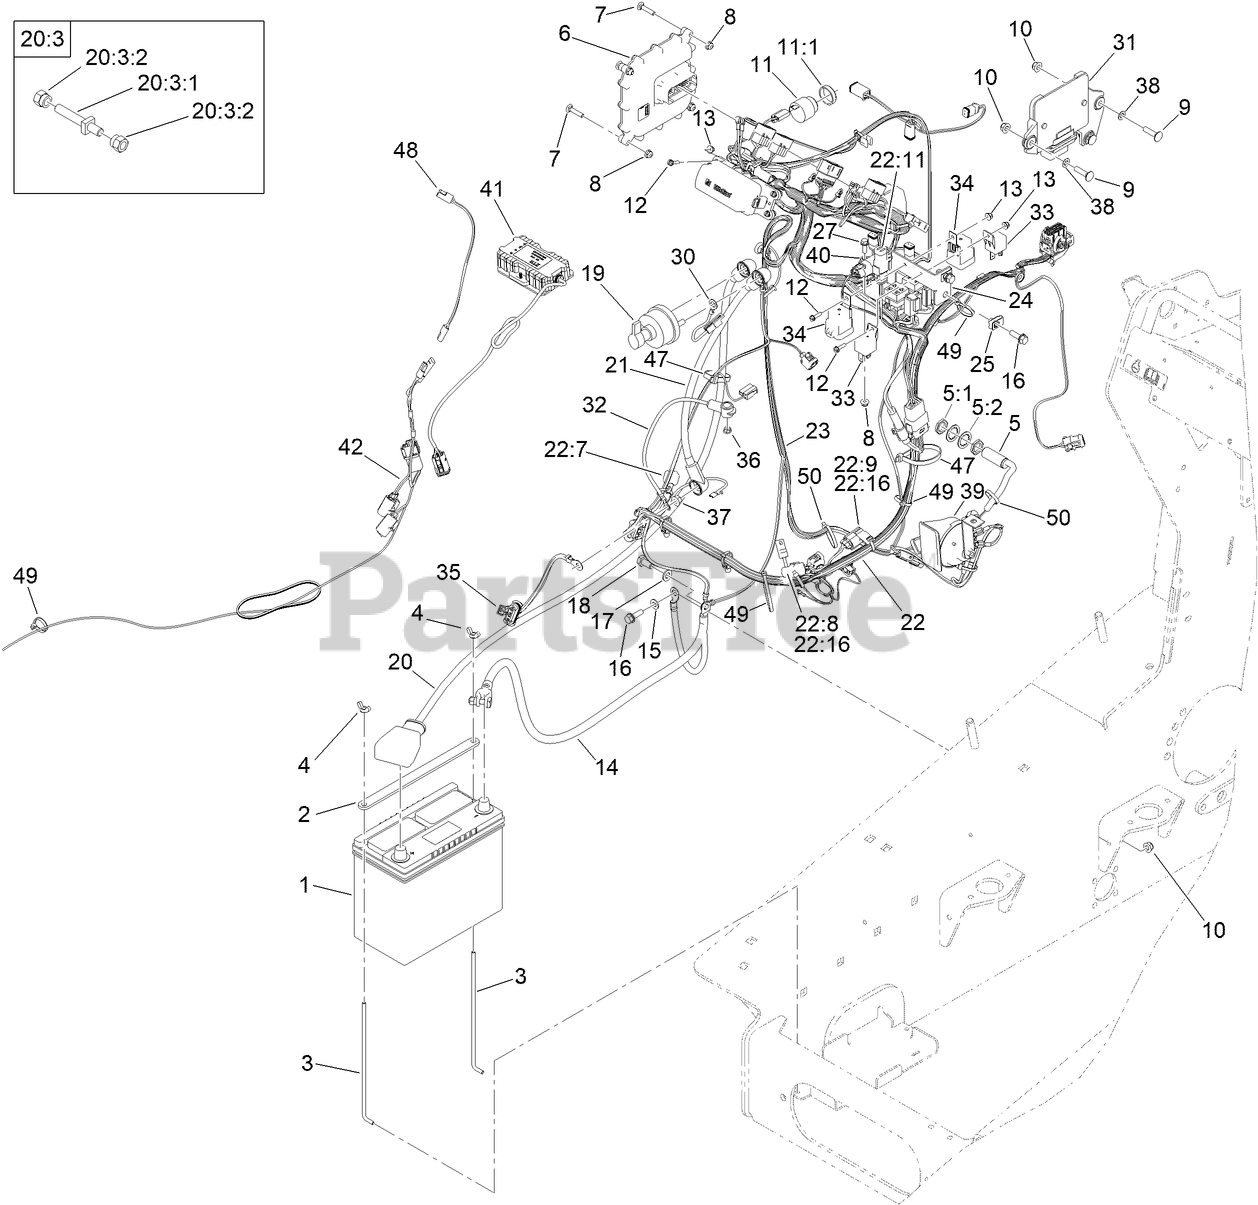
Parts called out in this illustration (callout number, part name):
1	BATTERY-GROUP 51
2	PLATE-HOLD DOWN, BATTERY
3	ROD-HOLD DOWN, BATTERY
4	NUT-WING
5	PROXIMITY SWITCH ASM
5:1	NUT-HEX
5:2	WASHER-LOCK, INTERNAL TOOTH
6	CONTROLLER
7	SCREW-CARR
8	NUT-HF
9	SCREW-CARR
10	NUT-HF, NI
11	AUDIO ALARM ASM
11:1	NUT-PLASTIC, KNURLED
12	SCREW-HWH
13	NUT-HF
14	CABLE-BATTERY, NEGATIVE
15	WASHER-PLAIN
16	SCREW-HHF
17	WASHER-FLAT
18	SCREW-HH
19	SWITCH-DISCONNECT, MASTER
20	CABLE-BATTERY, RD ASM
20:3	BOLT ASM
20:3:1	BOLT-CLAMP, BATTERY
20:3:2	NUT-CLAMP, BATTERY
21	CABLE-BATTERY, RD ASM
22	HARNESS-WIRE, ENGINE
22:8	FUSE-MINI BLADE, 2 AMP
22:9	FUSE-MINI BLADE, 10 AMP
22:11	CONNECTOR (6M)
22:16	COVER-FUSE, SINGLE
23	HARNESS-WIRE, MAIN
24	BRACKET-RELAY
25	NUT-CLIP, U
27	SCREW-HHF
30	HARNESS-WIRE, FUSIBLE LINK
31	CONTROLLER-ENGINE
32	HARNESS-WIRE
33	RELAY
34	RELAY-MINI
35	HARNESS-WIRE, FUSIBLE LINK
36	NUT-HF
37	NUT-HF
38	RING-RETAINING, BOLT
39	Horn And Bracket Assembly (Inc. Ref.# 44 45)
40	SENSOR-ATM
41	M7L-LITE ZTR KIT ASM
42	HARNESS-WIRE, MACHINE ZTR
47	TIE-CABLE
48	HARNESS-WIRE, SAE J928-2, 12" JUMPER
49	TIE-CABLE
50	TIE-CABLE
